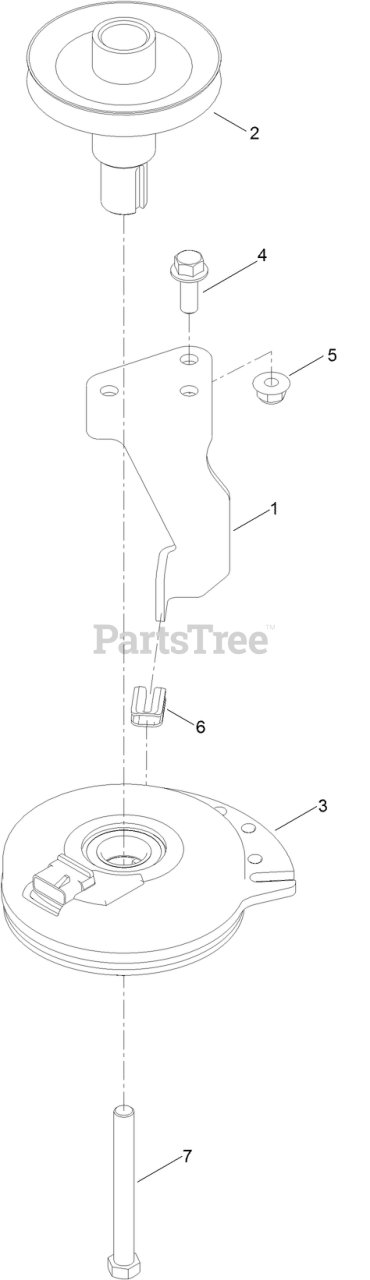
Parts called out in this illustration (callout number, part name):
1	STOP - CLUTCH (NARROW)
2	PULLEY-ENGINE
3	CLUTCH-ELECTRIC
4	SCREW-HHF
5	NUT-HF, NI
6	ISOLATOR-CLUTCH
7	SCREW-HH
